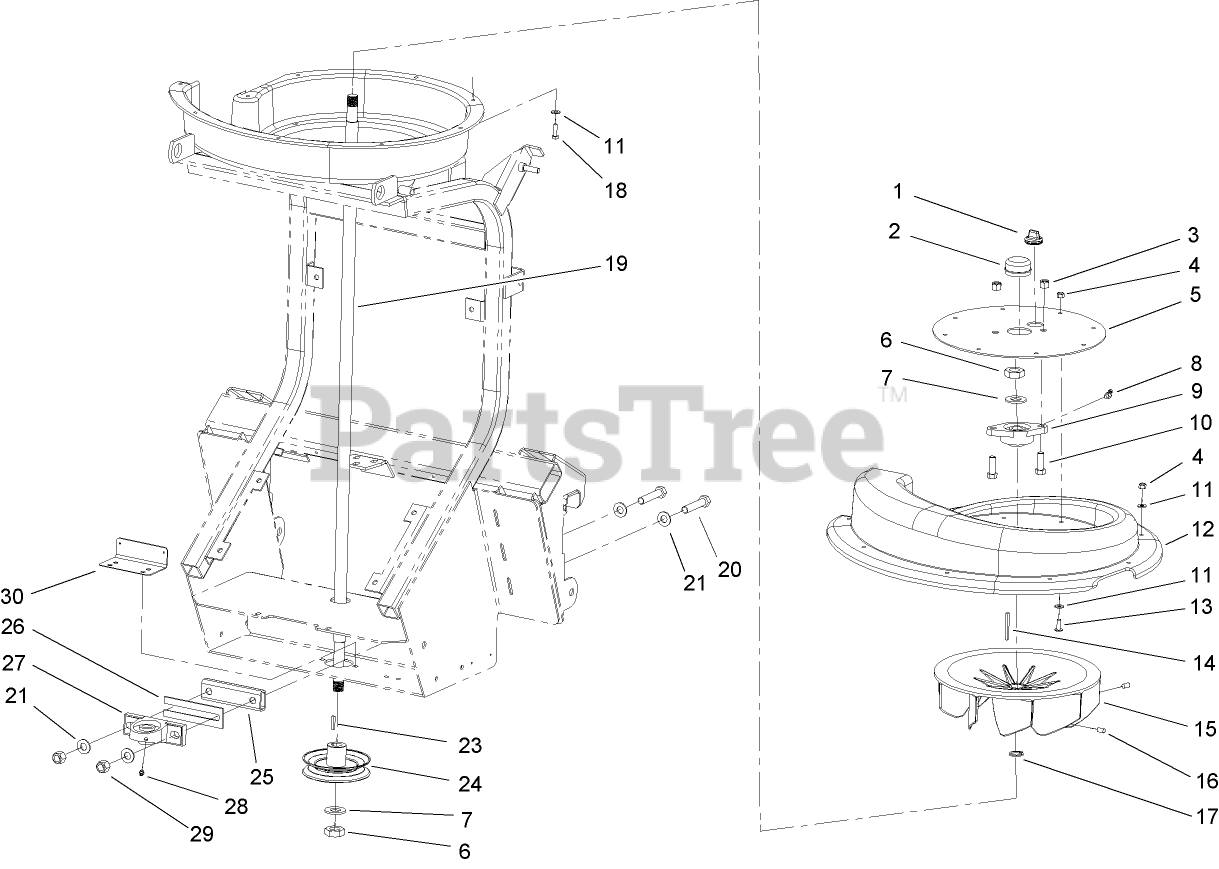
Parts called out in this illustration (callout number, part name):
2	CAP-GREASE
3	NUT-LOCK, NI
4	NUT-LOCK, NI
5	COVER-SCROLL
6	NUT-HEX
7	WASHER
8	FITTING-LUBE, 45 DEG
9	BEARING-FLANGE
10	SCREW-HH
11	WASHER-FLAT
12	SCROLL-TOP
13	SCREW-HEAD, TRUSS
14	KEY-SQUARE
15	FAN-BALANCING
16	SCREW-SET
17	RING-RETAINING, Ext
18	SCREW-HH
19	SHAFT-FAN
20	SCREW-HH
21	WASHER-FLAT
23	KEY-SQUARE
24	PULLEY-V
26	SPACER-BEARING (Use as required to tension belt.)
27	BEARING
28	FITTING-GREASE
29	NUT-LOCK, NI
30	TEMPLATE, BASE FRAME
